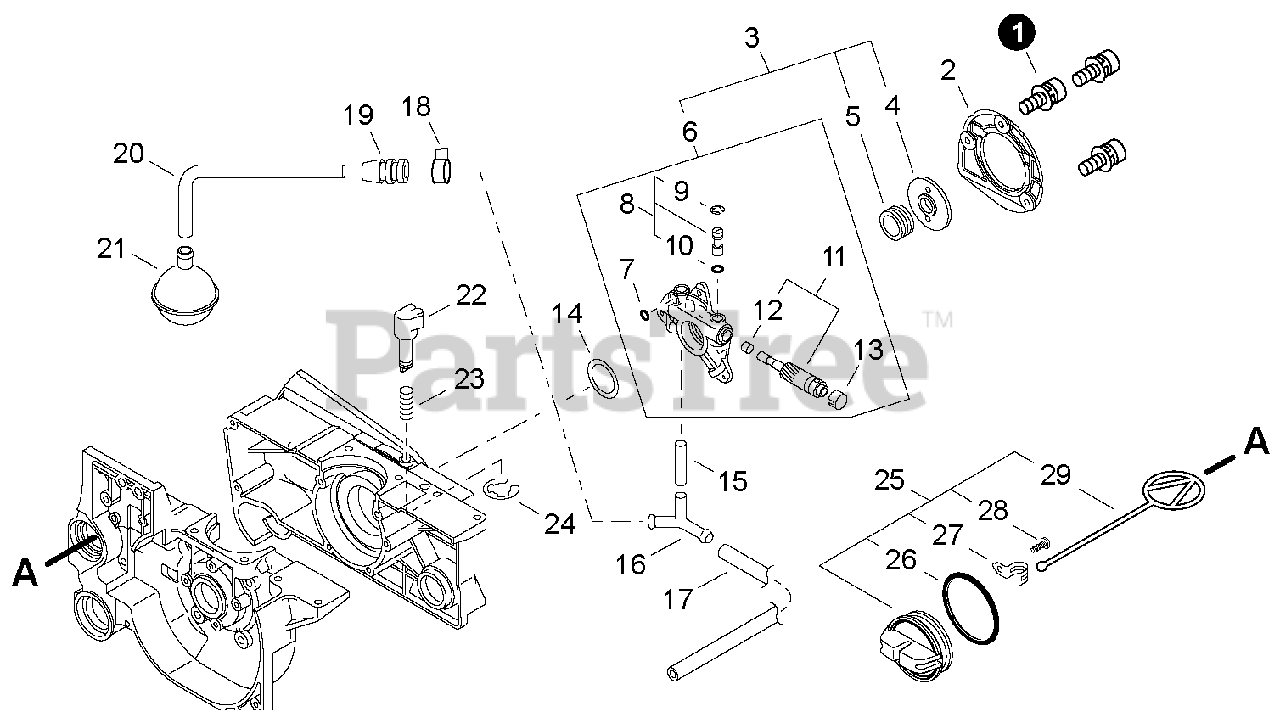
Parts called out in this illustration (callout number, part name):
1	SCREW - 4X12
2	COVER, OIL PUMP
3	AUTO-OILER KIT
4	WASHER - 12
5	GEAR - WORM
6	AUTO-OILER ASSY
7	O-RING - 3
8	CONTROL PIN ASSY
9	RING, RETAINING
11	PLUNGER KIT
13	CAP, PLUNGER
15	PIPE - 3X6X20 -- BLACK
16	CONNECTOR, PIPE
17	PIPE - 3X6X200 -- BLACK
18	CLIP - 6.5
20	PIPE - OIL
21	FILTER, OIL
22	DIAL, AUTO-OILER
24	RING, RETAINING - 3
25	CAP ASSY
26	O-RING - 25
27	RETAINER
28	SCREW - 3X8 -- TAPPING
29	CONNECTOR, CAP
